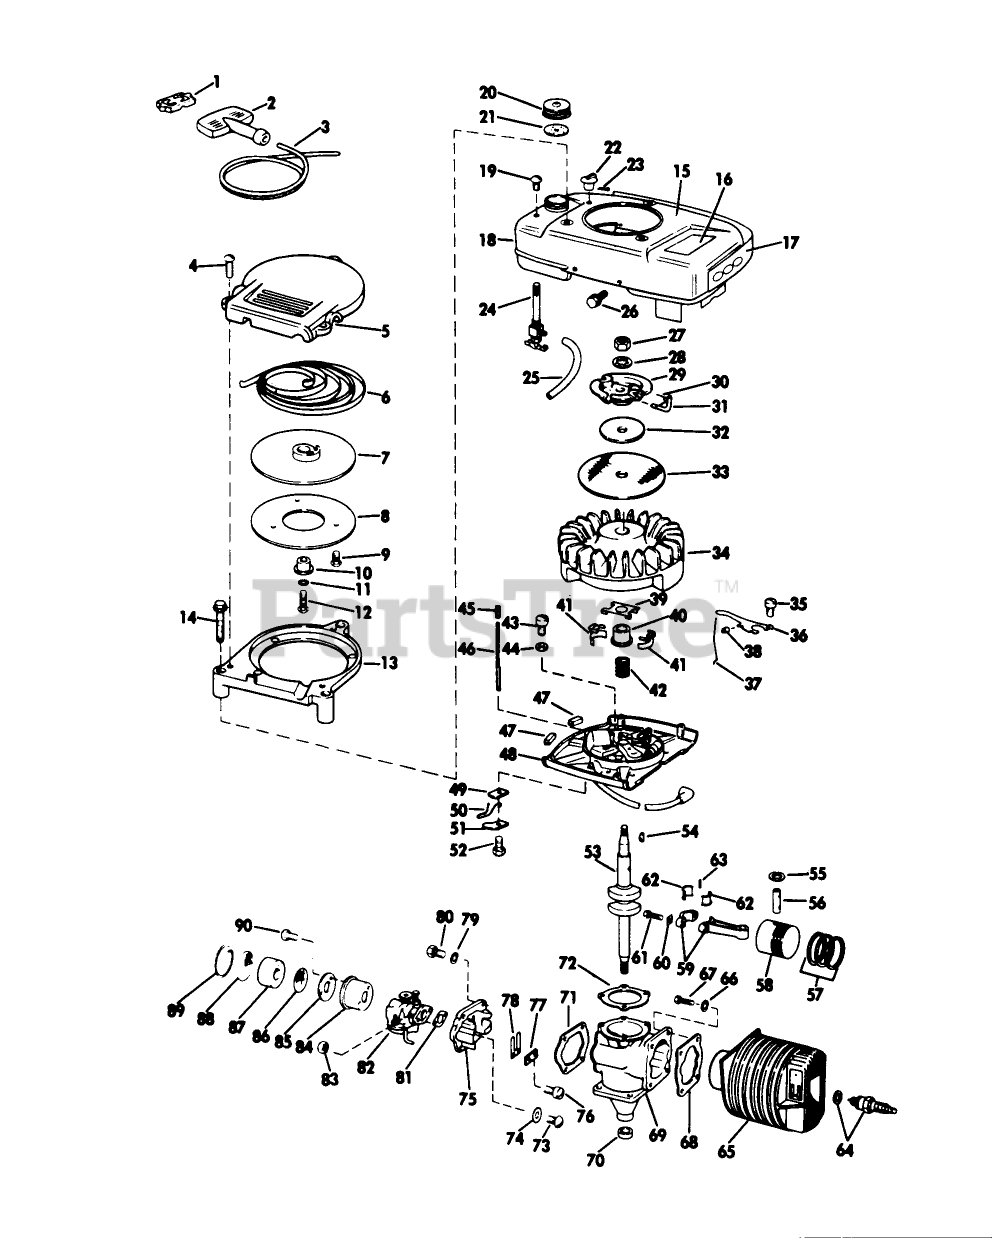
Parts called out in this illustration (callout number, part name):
6	RECOIL SPRING
20	Gas Cap
22	KNOB, CHOKE BAR
23	Cotter Pin-Choke Knob
24	VALVE&SCREEN SM
26	SCREW S
31	PIN - STARTER
36	GOVERNER LEVER AY
37	GOVERNOR ROD S
38	WEAR BLOCK S
40	COLLAR S
52	Screw Shut-off Switch
55	RING-RETAINING
62	LINER ASM
68	GASKET S
72	GASKET S
77	PLATE-BACKUP, REED
80	SCREW S
81	GASKET S
83	STOP NUT
85	BACK-UP PLATE
87	ELEMENT
